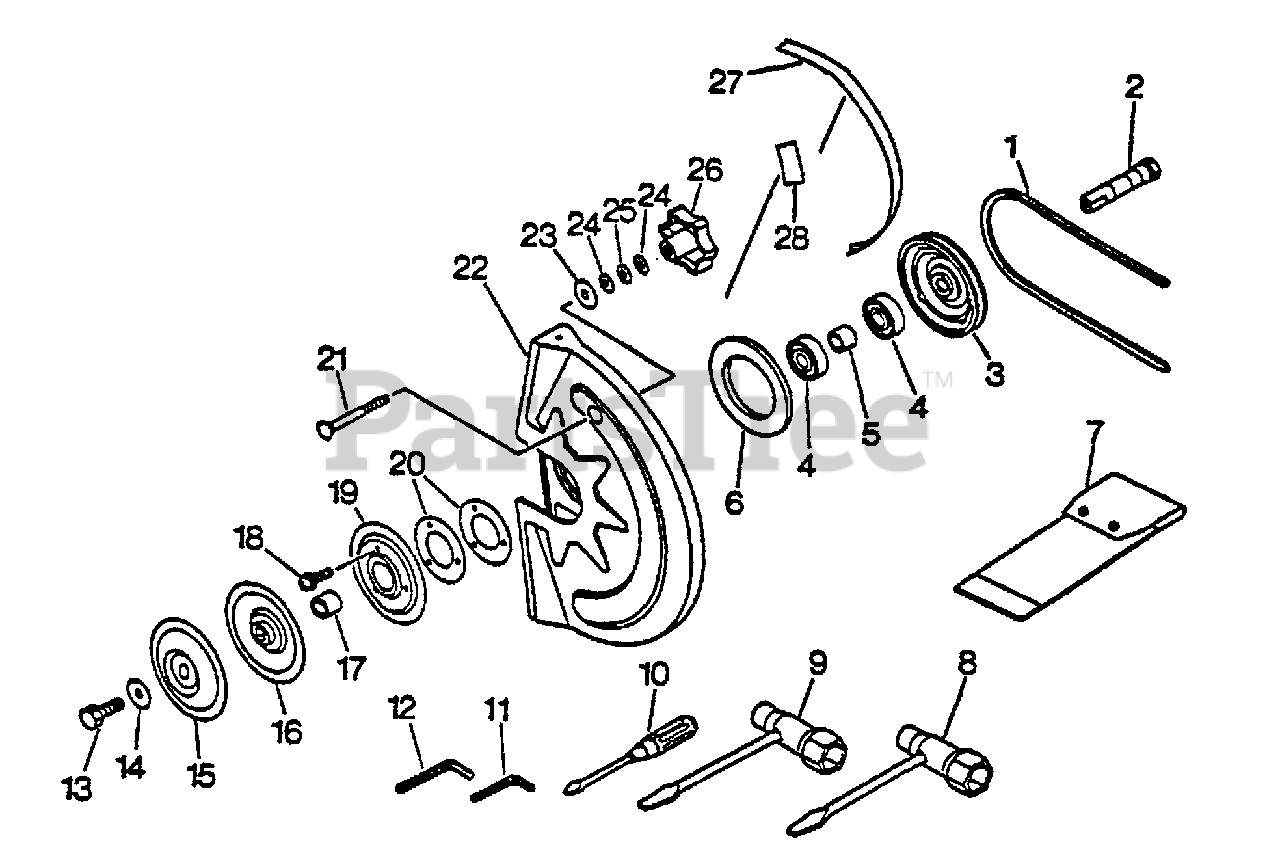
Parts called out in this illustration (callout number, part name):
4	BEARING, BALL 6203
5	SPACER
7	BAG, TOOL
8	T-WRENCH 13×19×180
9	WRENCH, T 17×19 MM
10	SCREWDRIVER, SLOTTED
11	WRENCH, ALLEN 4 MM
12	WRENCH, ALLEN 5 MM
15	FLANGE, CUTTER
16	FLANGE, CUTTER
18	SCREW 4×14
19	PLATE
22	COVER, BLADE
24	WASHER 10.5×18×1.6
25	WASHER, SPRING 10
27	LABEL
28	LABEL - ECHO
